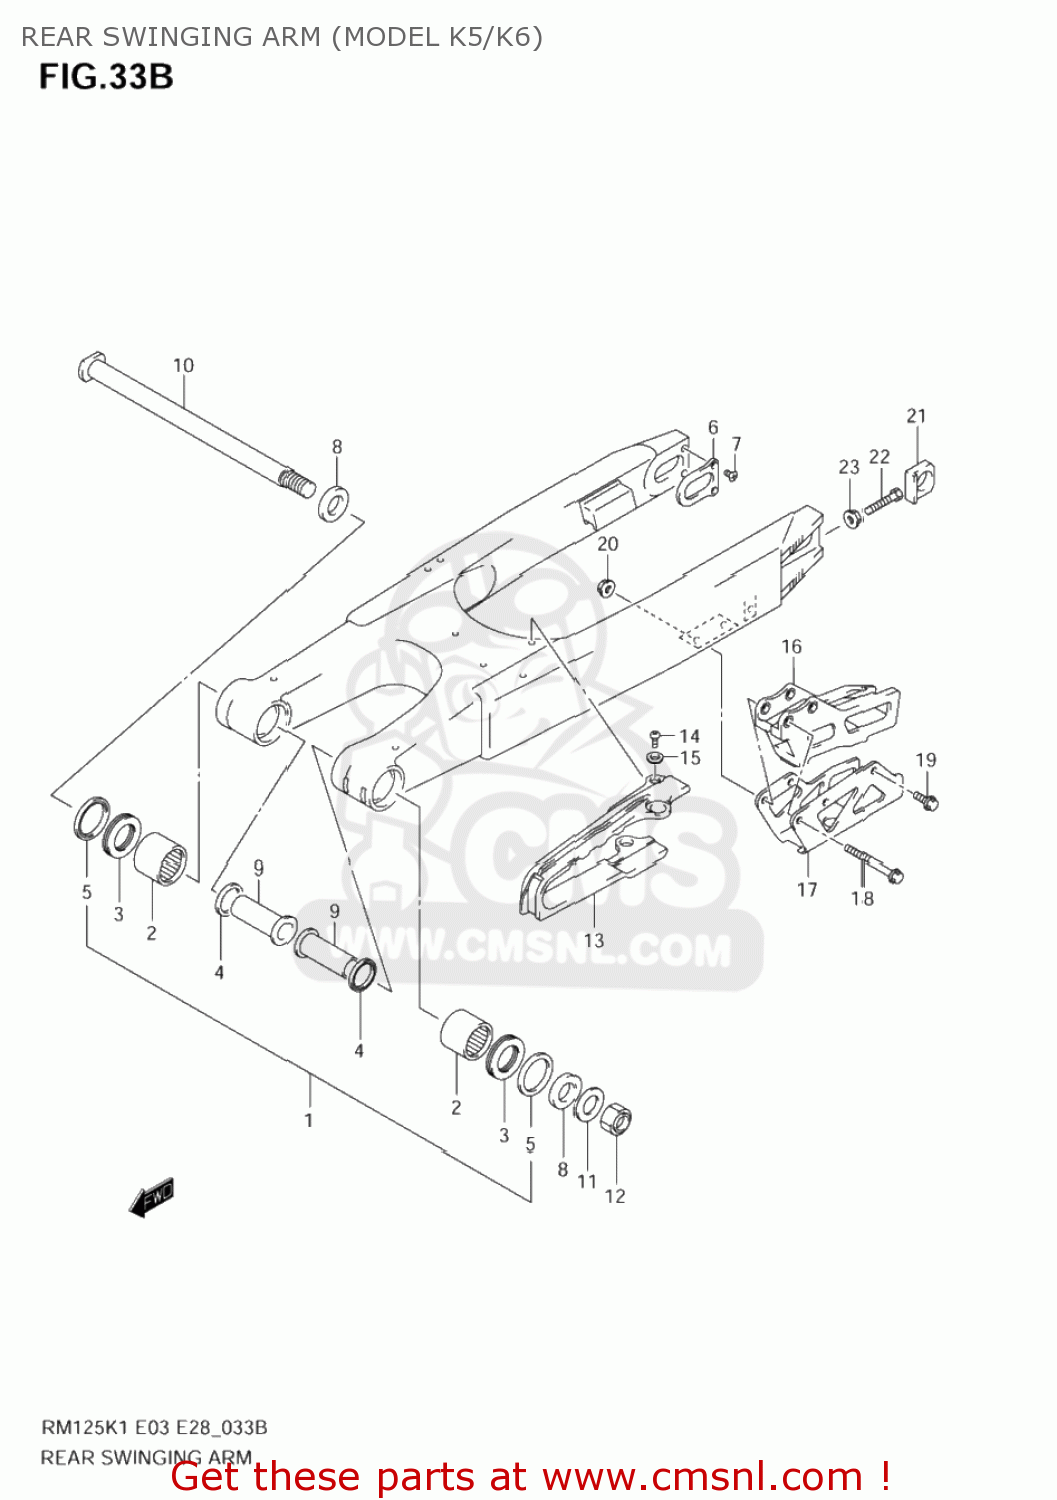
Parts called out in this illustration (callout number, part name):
1	SWINGINGARM ASSY,RR
2	BEARING(22X29X30)
3	BEARING(22X35X2)
4	SEAL,OIL(22X29X4)
5	SEAL,RR SWGARM PIVOT OUTER
6	PLATE,RR SWING ARM RR
7	SCREW,UPPER
8	SPACER,RR SWGARM PIVOT OUTER
9	SPACER,SWGARM PIVOT INNER
10	SHAFT,RR SWINGINGARM PIVOT
11	WASHER, FIXED DRIVE FACE
12	NUT
13	BUFFER,CHAIN TOUCH DEFENSE
14	SCREW
15	WASHER
16	GUIDE,CHAIN
17	PLATE,CHAIN GUIDE
18	BOLT(6X45)
19	BOLT(6X12)
20	NUT
21	WASHER,CHAIN ADJUSTER
22	BOLT(8X50)
23	NUT
